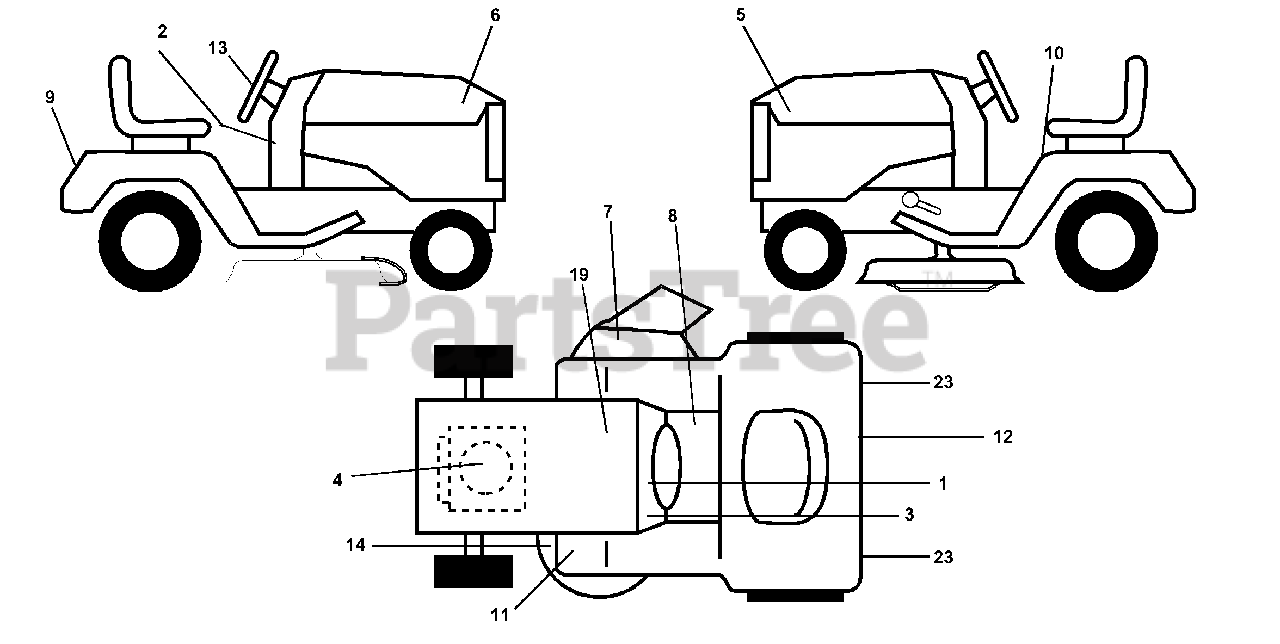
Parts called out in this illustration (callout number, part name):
1	Decal, Operating Instruction
2	Decal, Dash Logo
4	Decal, HP Engine
5	Decal, Hood LH
6	Decal, Hood RH
7	Decal,Warning
8	Decal, Brake Parking Saddle
9	Decal,Fender
10	Decal,Danger
11	Decal, Clutch/Brake
12	Decal, D-Bar Ctrl. Mvt Hyd YT/GT
13	Decal,Wheel Steering
14	Decal, V-Belt Schematic
19	Decal, Battery
23	Reflector, Taillight
